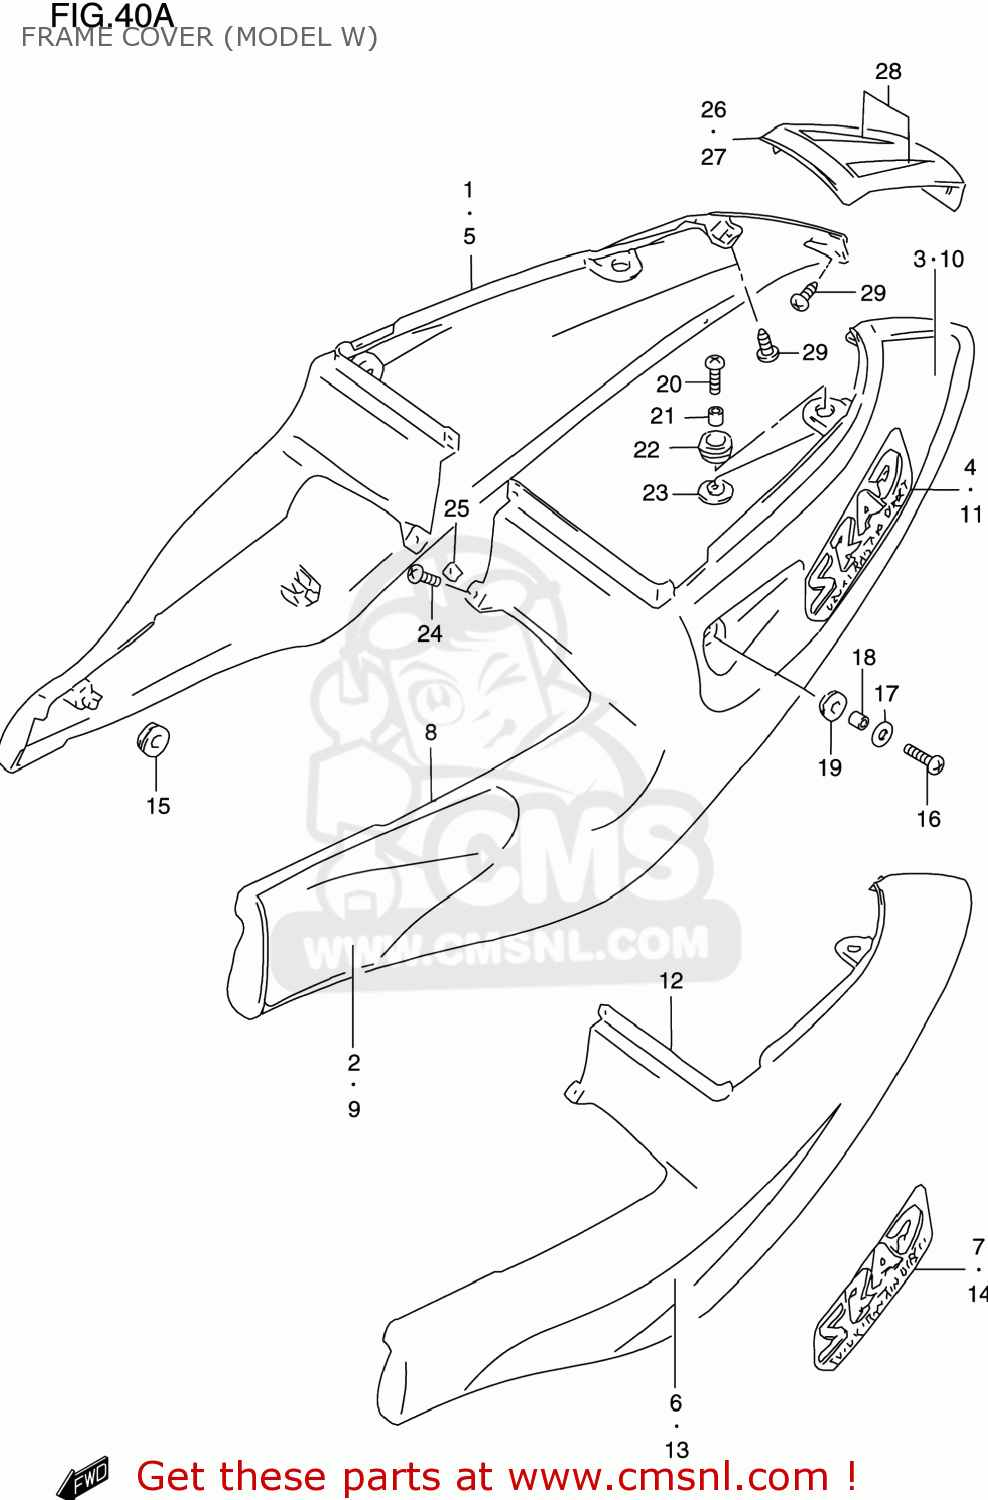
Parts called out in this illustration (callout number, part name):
1	COVER,FRAME,R(BLACK)
2	TAPE,FRAME COVER,RIGHT NO
3	TAPE,FRAME COVER,R
4	EMBLEM,FRAME COVER
5	COVER,FRAME,R(WHITE)
6	TAPE,FRAME COVER,RIGHT
7	EMBLEM,FRAME COVER
8	COVER,FRAME,L(BLACK)
9	TAPE,FRAME COVER NO.1,L
10	TAPE,FRAME COVER,L
11	EMBLEM,FRAME COVER
12	COVER,FRAME,L(WHITE)
13	TAPE,FRAME COVER,LEFT
14	EMBLEM,FRAME COVER
15	CUSHION
16	SCREW(6X20)
17	WASHER(6.5X22X1.6)
18	SPACER(6.5X9X6.7)
19	CUSHION
20	SCREW(6X25)
21	SPACER(6.5X10X9.4)
22	CUSHION,TAIL COVER UPR
23	CUSHION,FRAME COVER LWR
24	SCREW
25	NUT
26	COVER,FRAME CTR
27	COVER,FRAME CTR
28	TAPE SET,FRAME COVER CTR
29	SCREW
